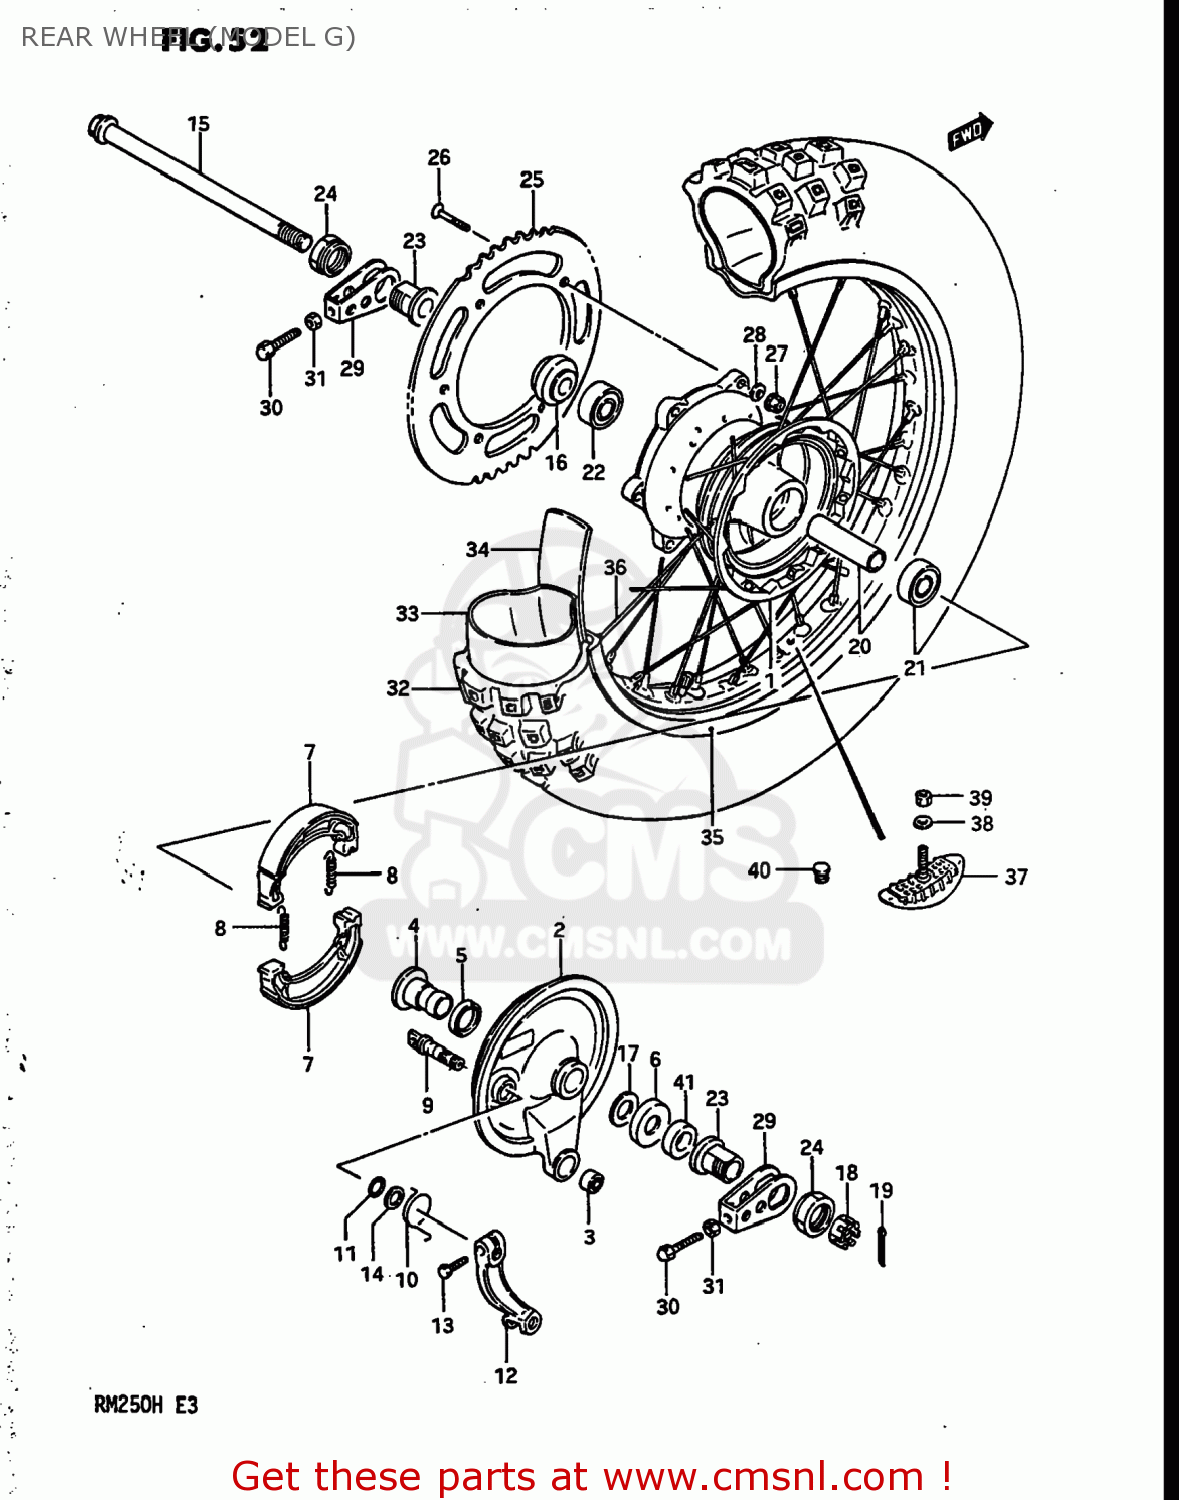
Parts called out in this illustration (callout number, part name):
1	DRUM,REAR HUB
2	PANEL SET
3	SPHERICAL BRNG,TORQUE LINK
4	SPACER,REAR HUB PANEL
5	SEAL,OIL(24X31X5)
6	CVR,RR BRAKE AHR PNL DUST SEAL
7	SHOE,BRAKE
8	SPRING,BRAKE SHOE
9	CAM,FR BRAKE
10	SPRING
11	O RING(D:2.5,ID:11.4)
12	LEVER,RR BRAKE CAM
13	BOLT
14	WASHER(12.5X20X1)
15	AXLE,REAR
16	SPACER COMP,REAR AXLE
17	WASHER
18	NUT
19	PIN,COTTER
20	SPACER,REAR HUB BEARING
21	BEARING
22	BEARING
23	SPACER,CHAIN ADJUSTER
24	NUT
25	SPROCKET,REAR
26	SCREW(8X40)
27	NUT
28	WASHER
29	ADJUSTER,CHAIN
30	BOLT(8X43)
31	NUT
32	TIRE
33	TUBE,INNER
34	PROTECTOR,WHEEL,INNER
35	RIM,REAR WHEEL (2.15X18)(A
36	SPOKE ASSY, REAR
37	STOPPER,BEAD
38	WASHER
39	NUT 8MM
40	CAP(OD:12)
41	SPACER,AXLE RH
